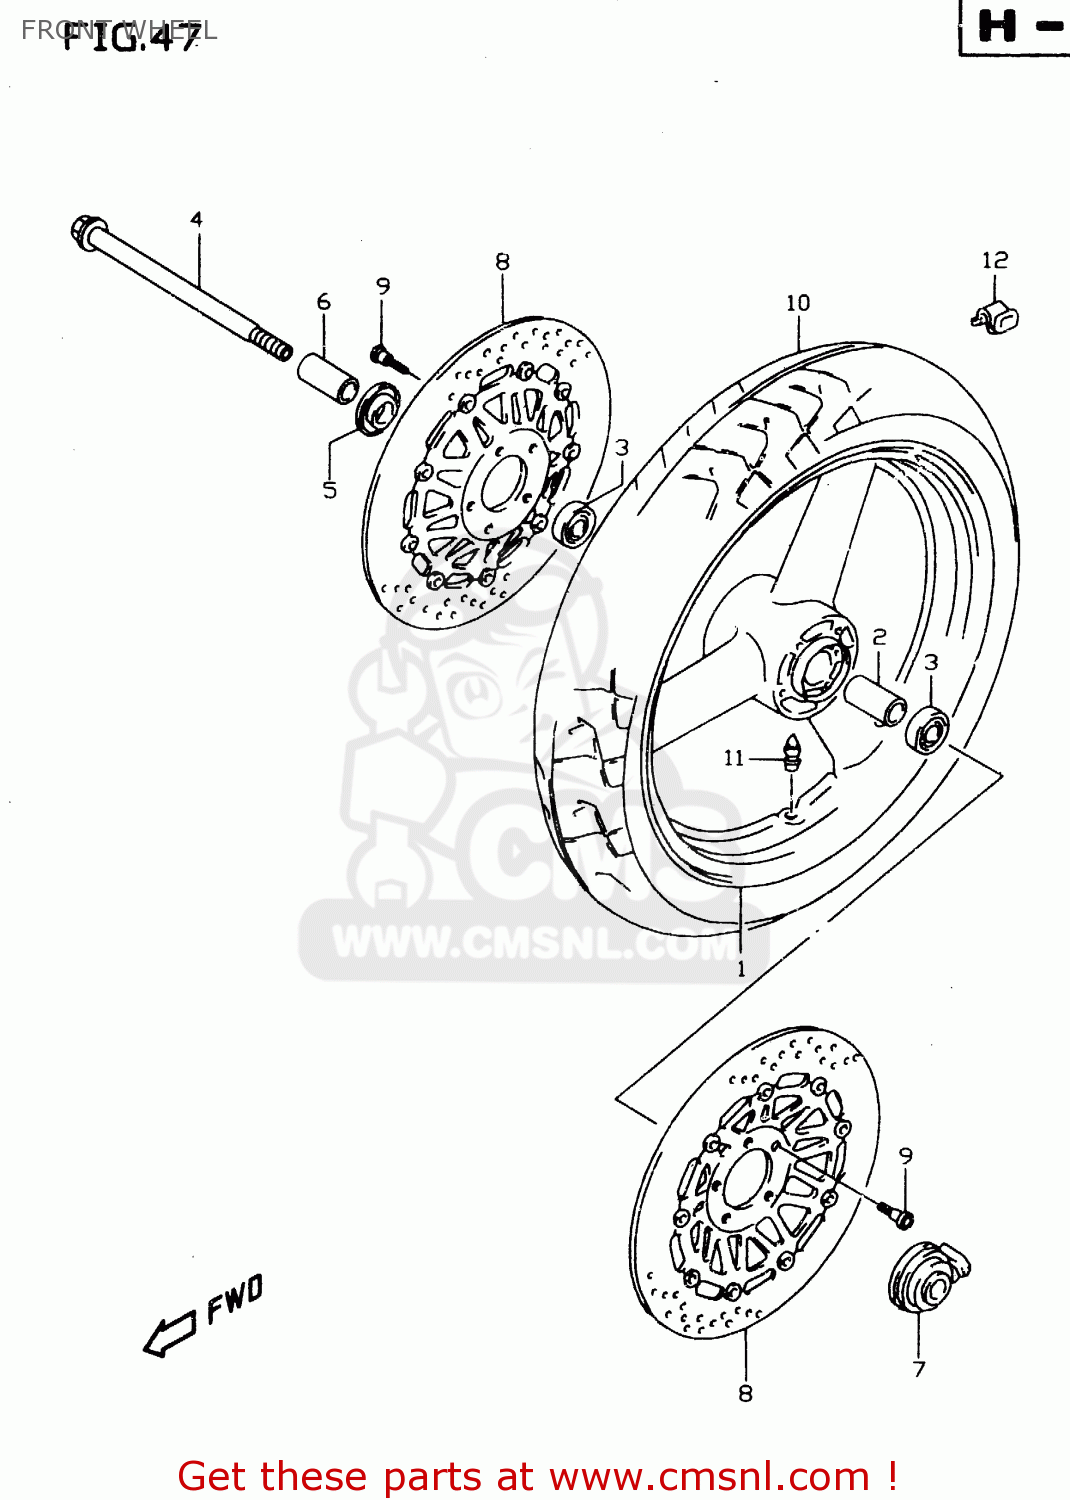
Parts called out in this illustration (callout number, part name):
1	WHEEL,FRONT (17XMT3.50)(
2	SPACER(20.8X27.2X74)
3	BEARING
4	AXLE,FR
5	SPACER,FR HUB BEARING,R
6	SPACER,FR AXLE,R
7	BOX ASSY,SPEEDOMETER GEAR
8	DISC,FR BRAKE
9	BOLT 8X33
10	TIRE,FR(120/70 ZR17 58W)
11	VALVE ASSY,WHEEL RIM(TR412)
12	BALANCER,WHEEL (10G)
